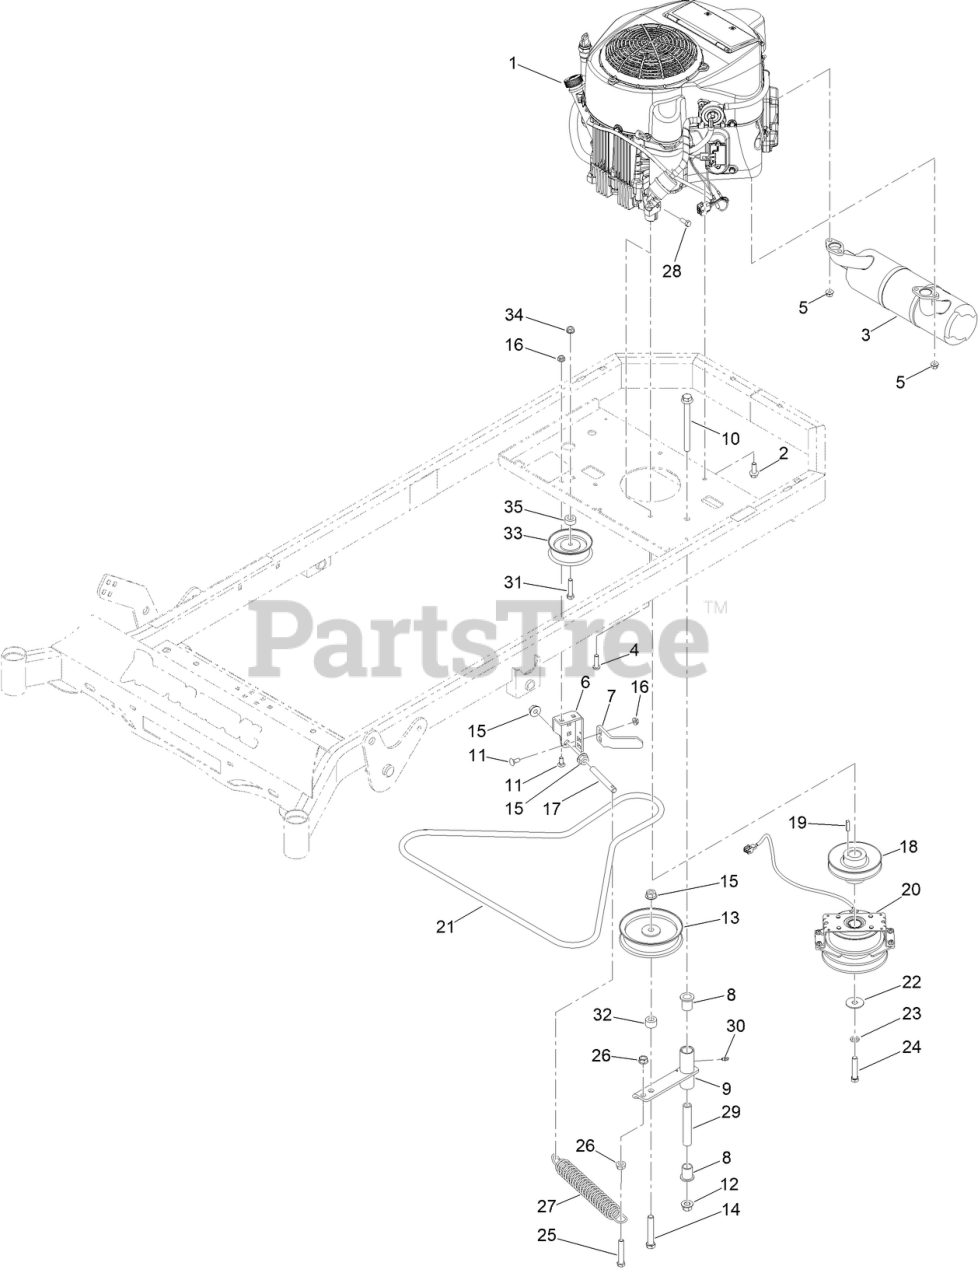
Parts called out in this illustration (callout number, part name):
1	KAWASAKI FR691V ENGN
2	3/8-16 X 1-1/8 IND HWH W/SERR TRI LOB ZY
3	2019 EXHAUST SYST FOR KAWI FR FS AND FT
4	3/8-16 X 1-1/4 PAN TORX (TRI-LOB) TRS ZC
5	NUT-HF
6	MWR PUMP IDLER TENSIONING BRKTPAINTED
7	2021 TTQ MWR OGURA CLUTCH BRKT PAINT
8	3/4IN ID X15/16IN OD X 1-1/8IN FLNG BUSH
9	MWR PUMP IDLER ASSY PAINTED
10	1/2-13 X 5-1/2 HEX FLANGE BOLT GR 8 ZY
11	BOLT-CARR
12	NUT-LOCK
13	5-3/4IN IDLER PULLEY 7/16IN SPACER ASSY
14	1/2-13 X 3 HEX C/S GR 5 ZINC W/LOCTITE
15	NUT-HHF
16	NUT-HF
17	MWR PUMP IDLER SPRING TENSIONER
18	MWR HYDRAULIC PUMP DRIVE PULLEY (B-BELT)
20	MWR TTQ OGURA CLUTCH
21	MWR TTQ PUMP BELT
22	1/2IN X 1-5/8 BELLEVILLE CUP WASHER YZ
23	WASHER-LOCK
24	TTQ CLUTCH BOLT
26	NUT-HF
27	MWR DECK SPRING
28	M8-1.25 X 20MM HEX FLANGE BOLT ZINC 10.9
29	MWR INNER IDLER SPACER
30	1/4IN DRIVE TYPE GREASE FITTING YZ
31	SCREW-HH
32	.530 ID/ 1IN OD X .625 PUMP IDLER SPACER
33	4IN DIESEL AND ECONOMY MWER IDLER PULLEY
34	NUT-HHF, WHIZ
35	MWR PULLEY SPACER
